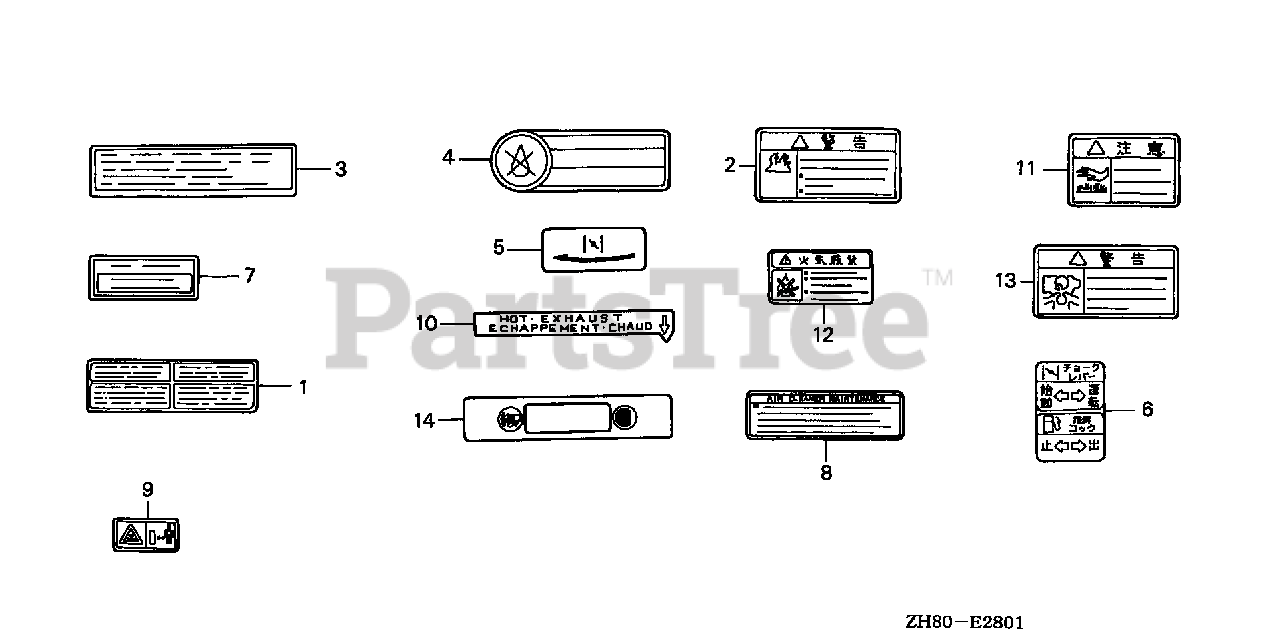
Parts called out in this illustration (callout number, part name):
1	MARK, CAUTION (PUMP)
7	MARK, OIL ALERT (ENGLISH)
11	LABEL, CAUTION (ENGLISH, ETC.)
